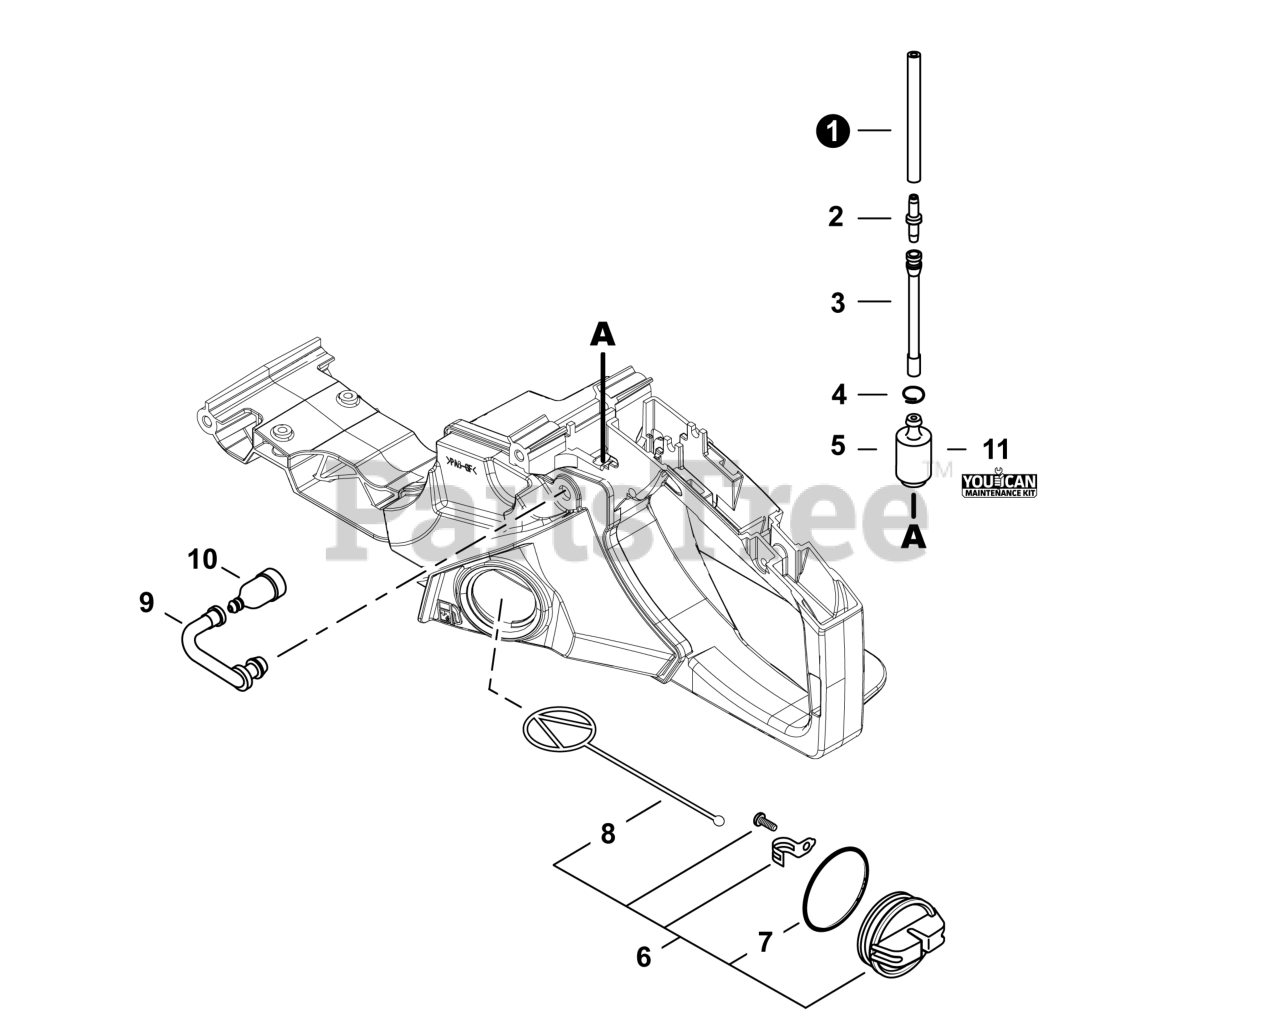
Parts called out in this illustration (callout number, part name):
1	PIPE, FUEL 3×6×75
2	CONNECTOR, PIPE
3	PIPE, FUEL
4	CLIP Ø6
5	FILTER, FUEL
6	CAP ASSY, FUEL
7	O-RING 29
8	RETAINER, CONNECTOR
9	SCREW, TAPPING 3×8
10	FUEL CAP CONNECTOR (L=60MM)
11	PIPE, FUEL VENT, CS-490/501
12	VENT ASSY
13	TUNE-UP KIT - YOUCANT
